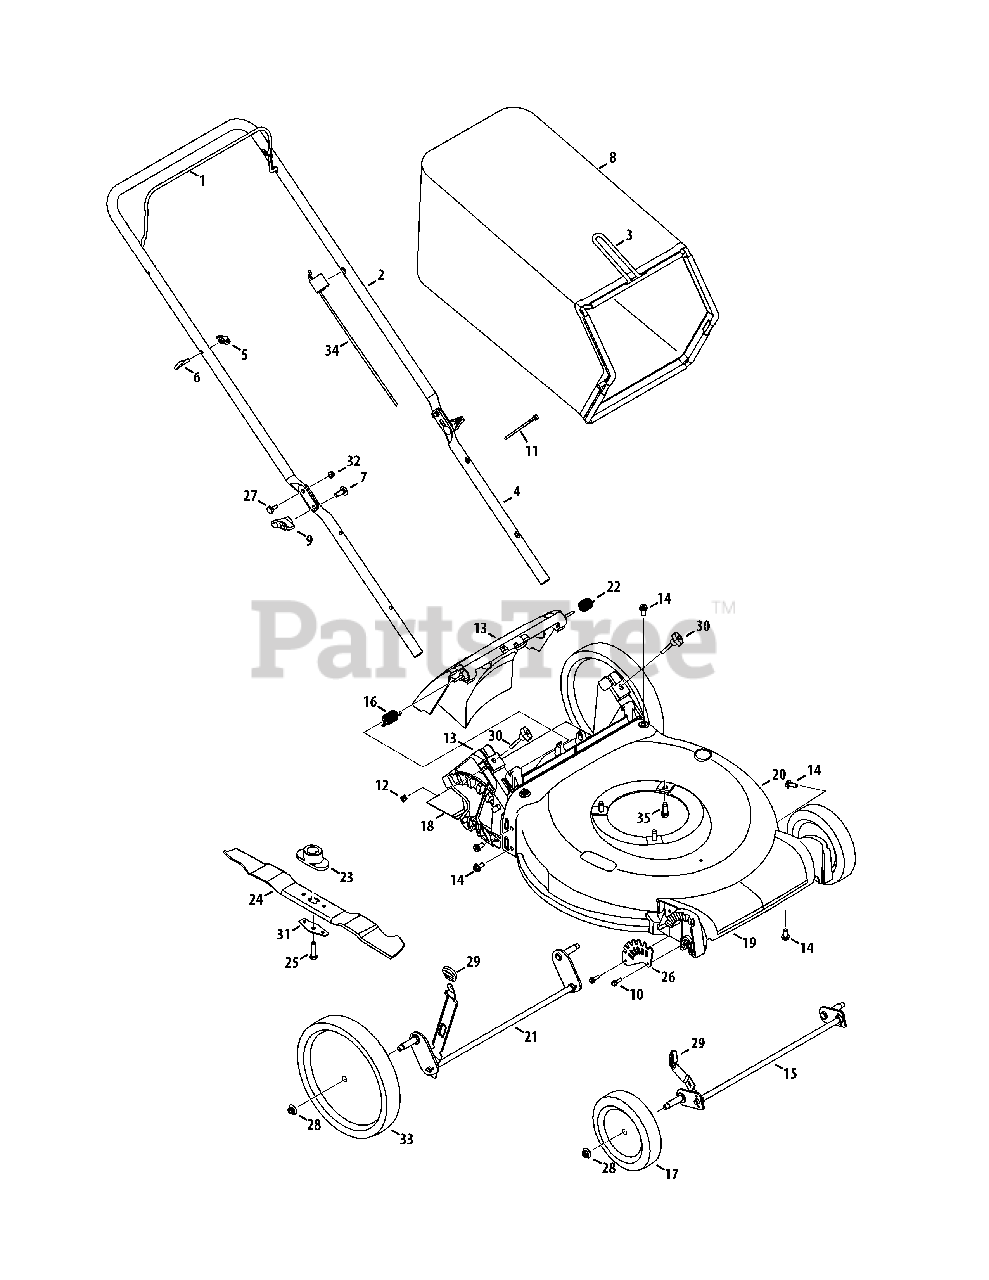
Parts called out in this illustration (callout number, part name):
1	Blade Control
2	Upper Handle
3	Grass Catcher Frame
4	Lower Handle
5	Wing Nut
6	Rope Guide
7	Carriage Screw ,5/16-18
8	Grass Bag
9	Wing Knob
10	Screw, 1/4-15 x .750
11	Cable Tie
12	Nut, Sq., 1/4-20
13	Rear Discharge Door Assembly
14	Screw, 5/16-14 x .750
15	Front Axle Assembly
16	Torsion Spring - RH
17	Front Wheel Gray
18	Trail Shield
19	Front Cover
20	Deck - 21"
21	Rear Axle Assembly
22	Torsion Spring - LH
23	Blade Adapter
24	Mulching Blade
25	Screw , 3/8-24 x 1.50
26	Front Height Adjuster Plate
27	Sldr. Screw, .375 x .126 x 1/4-20
28	Flange Lock Nut, 3/8-16
29	Adjustment Lever Knob
30	Wing Nut
31	Blade Bell Support
32	Nut, Flange Lock, 1/4-20
33	Rear Wheel
34	Control Cable, 37.58"
35	TT Sems Screw, 3/8-16 x 1.0
